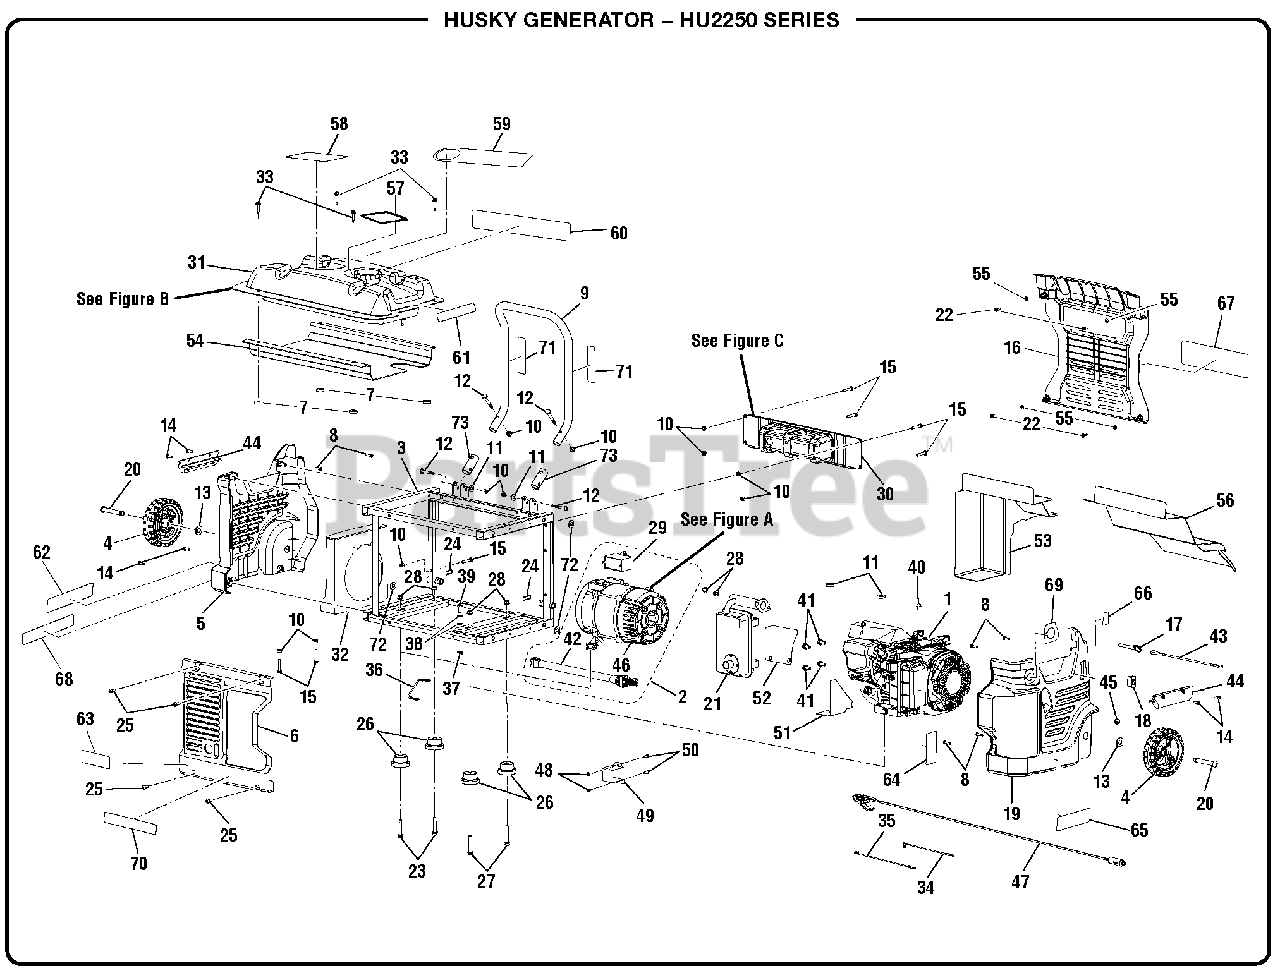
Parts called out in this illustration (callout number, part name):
2	Generator Head w/Capacitor
3	Frame Assembly
5	Panel Cover
6	Service Panel
7	Nylon Washer (D20 x D8 x 4.5t)
8	Screw (#9-18 x 20 mm)
9	Handle Assembly
10	Lock Nut (1/4-20)
11	Washer (1/4 in.)
12	Bolt (1/4-20 x 2 in., Hex Hd.)
13	Washer (1/2 in.)
14	Screw (12-14 x 15 mm)
15	Screw (1/4-20 x 1-3/4 in., T30 Torx Hd.)
16	Control Panel Cover
17	Release Pin
19	Outer Panel
20	Wheel Axle
21	Muffler Assembly
22	Screw (#9-18 x 15 mm)
23	Bolt (M8 x 45 mm, Hex Flange Hd.)
24	Axle Clip
25	Screw (1/4-20 x 1/2 in.)
26	Rubber Foot
27	Bolt (M8 x 50 mm)
28	Lock Nut (M8)
29	Capacitor
30	Control Panel Assembly
31	Fuel Tank Assembly
32	Intake Heat Shield
33	Screw (10-16 x 1 in.)
34	White Lead Assembly (18 Ga.)
35	Brown Lead Assemly (18 Ga.)
36	Ground Wire Assembly
37	Flange Nut (15/16-18)
38	Star Washer (5/16 in.)
39	Bolt (5/16-18 x 3/4 in.)
40	Bolt (M6 x 10 mm)
41	Bolt (5/16-24 x 5/8 in.)
42	Pigtail (Male Connector w/Wire)
43	Lanyard (3/16 in.)
44	Handle Grip
45	Recoil Rope Guide
46	Generator Head Assembly
47	Battery Cable Assembly
48	Lock Nut (M5)
49	Capacitor Holder
50	Bolt (M5 x 16 mm, Pan Hd.)
51	Heat Shield (Engine Air Inlet)
52	Heat Shield (Separator)
53	Heat Shield (Muffler)
54	Heat Shield (Under Fuel Tank)
56	Heat Shield
57	E85 Label
58	CPSC Label
59	Engine Warning Hangtag
60	Danger Label
61	Fire Danger Label
62	Ground Warning Label
63	Hot Surface Label
64	Starting Instructions Label
65	Data Plate
66	Engine Switch Label
67	Logo Label
68	Combustion Label
69	Fuel Valve Label
70	Engine Lubricant Label
71	Hot Handle Warning Label
